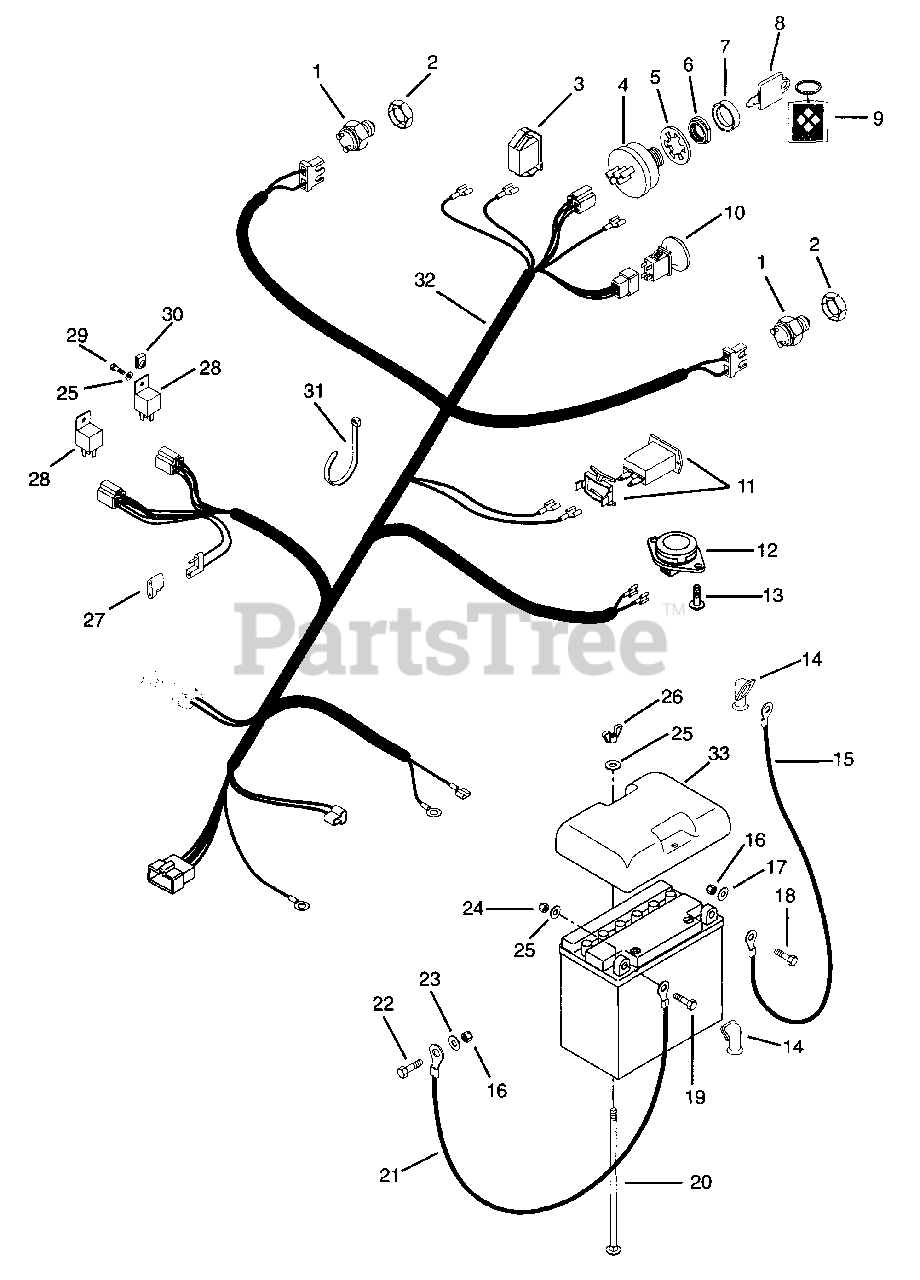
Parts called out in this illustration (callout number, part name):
1	Switch-Neutral Start N.O.
2	Nut-Stamped .56-18
3	Light, Indicator
4	Key Switch
5	Washer-Locking-Internal .563 x .040
6	Nut-Panel .562-24
7	Cap-Ignition Switch
8	Ignition Switch Key
9	Key Chain
10	Mount Plate, Transaxle Right Hand
11	Hour Meter
12	Switch-Seat
13	Screw-Machine .25-20 x .50
14	Boot, Insulator
15	Start Cable 22"
16	Nut-Locking-Nylon .312-18 Grade 2
17	Washer-Flat-Steel .344 x .688 x .065
18	Bolt-Hex .31-18 x 1.00 Grade 5
19	Bolt-Hex .25-20 x .75 Grade 5
20	Bolt-Round Head Square Neck .25-20 x 7.00
21	Cable, Negative Battery
22	Bolt-Hex .312-18 x .750
23	Washer-Flat-Steel .312 x .734 x .065
24	Nut-Locking-Nylon .250-20 Grade 2
25	Washer-Flat-Steel .281 x .620 x .065
26	Nut-Wing .250-20
27	Molded Diode Plug
28	Relay
29	Bolt-Hex .25-20 x .75 Grade 5
30	Nut-Retainer .25-20 x .56
31	Tie Wrap, Black
32	Harness, Wiring 18 HP Kohler
33	CVR-Battery
